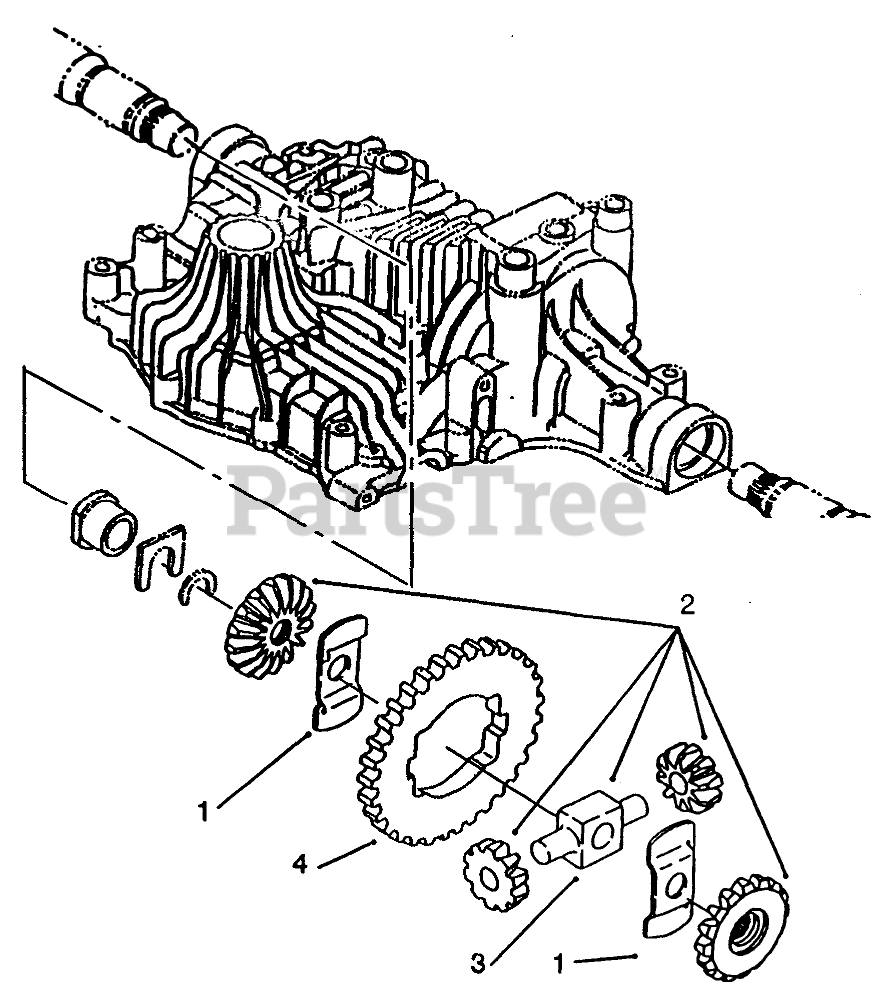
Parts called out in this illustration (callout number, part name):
1	Washer-Thrust (Only On: 72083,72048,72103,72063)
2	Differential Gear ASM (Only On: 72083, 72043, 72103, 72063)
3	Shaft-Pinion (Only On: 72083,72043,72103,72063)
4	Gear-Final (Only On: 72083,72043,72103,72063)
